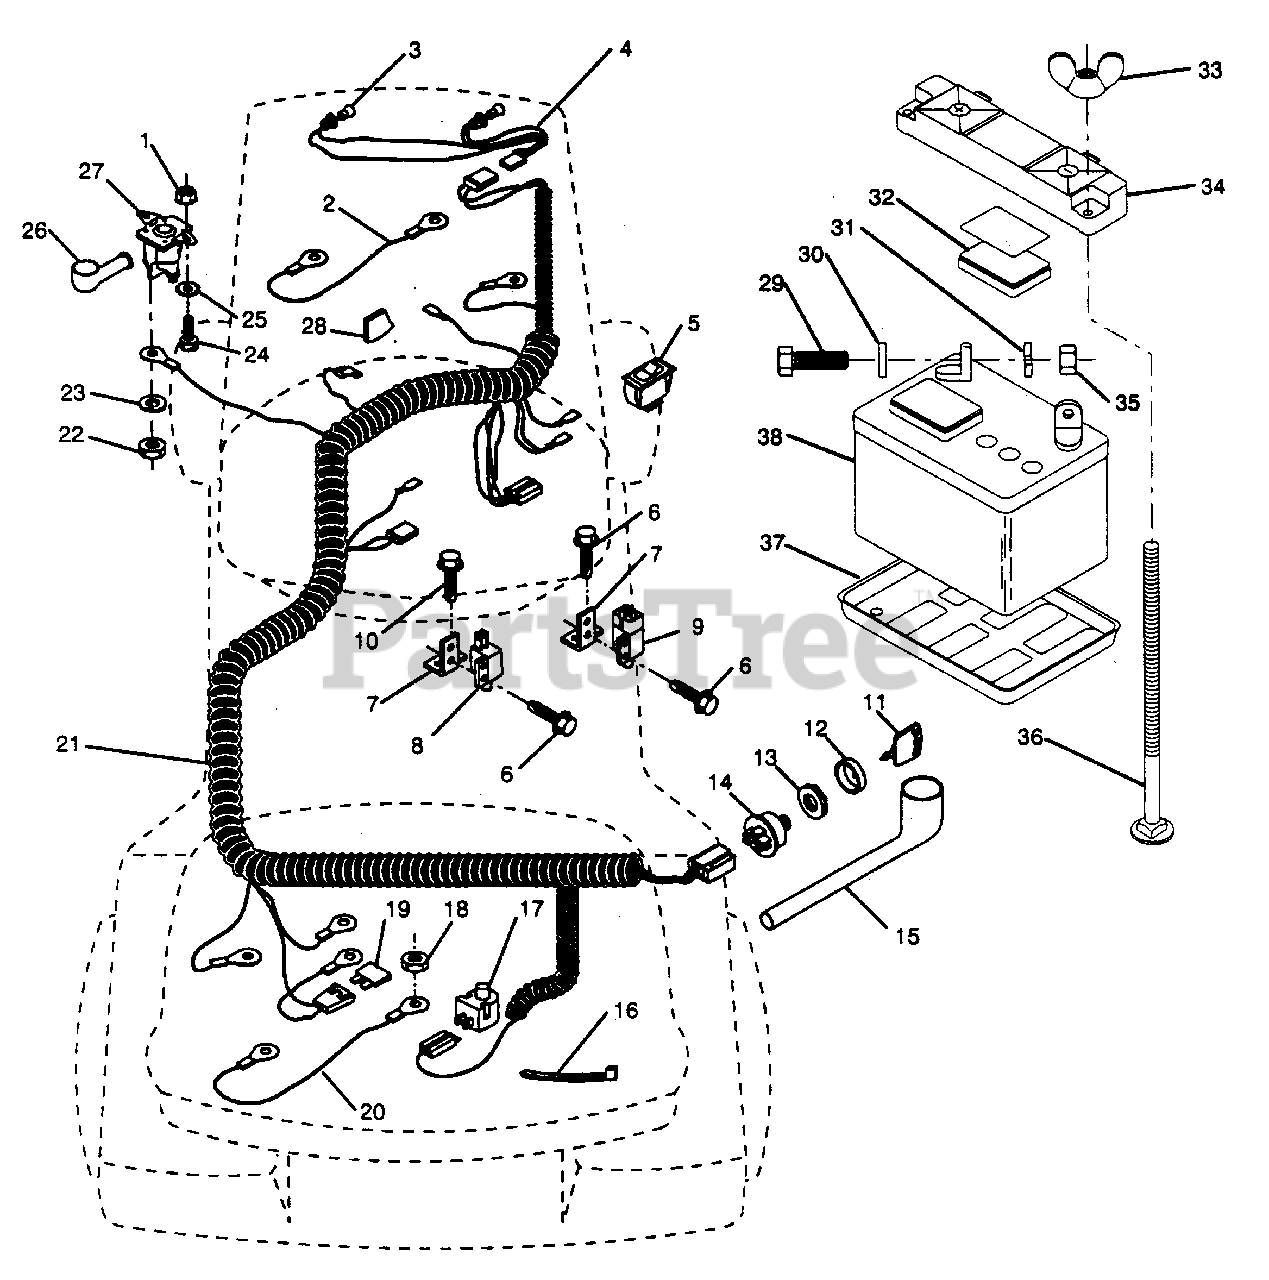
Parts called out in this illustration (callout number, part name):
1	Nut, Hex Keps 1/4-20 (AYP part number)
2	Assembly, Cable (AYP part number)
3	Bulb, Light (AYP part number)
4	Harness, Light Socket (AYP part number)
5	Switch, Light (AYP part number)
6	Screw, Tap Hex #10-24 x 1/2 (AYP part number)
7	Bracket, Switch (AYP part number)
8	Switch, Interlock (Clutch/Brake) (AYP part number)
9	Switch, Interlock (Attachment) (AYP part number)
10	Screw, Hex Wsh. Tap #10-16 x 1/2 (AYP part number)
11	Key, Molded (AYP part number)
12	Cover, Key Ignition (AYP part number)
13	Nut, Ignition (AYP part number)
14	Switch, Ignition (AYP part number)
15	Cover, Ignition Switch (AYP part number)
16	Tie, Cable (AYP part number)
17	Switch, Plunger (AYP part number)
18	Nut Keps 5/16-18 (AYP part number)
19	Fuse (AYP part number)
20	Assembly, Cable (AYP part number)
21	Harness, Ignition (AYP part number)
22	Nut, Hex Jam 1/4-20 (AYP part number)
23	Washer, Lock 1/4 (AYP part number)
24	Bolt, Fin. Hex 1/4-20 UNC x 1/2 Gr.5 (AYP part number)
25	Washer, Lock Ext. Tooth 1/4 (AYP part number)
26	Cover, Terminal (AYP part number)
27	Solenoid (AYP part number)
28	Stop, Choke (AYP part number)
29	Bolt, Hex 1/4-20 UNC x 3/4 (AYP part number)
30	Washer 9/32 x 5/8 x 16 Ga. (AYP part number)
31	Washer, Lock Hvy. Helical Spring 1/4 (AYP part number)
32	Cap, Battery (AYP part number)
33	Nut, Wing, Plastic, Locking 1/4-20 (AYP part number)
34	Guard, Terminal (AYP part number)
35	Nut, Fin. Hex 1/4-20 UNC (AYP part number)
36	Bolt, Carriage 1/4-20 UNC x 7-1/2 (AYP part number)
37	Tray, Battery (AYP part number)
38	Battery (AYP part number)
